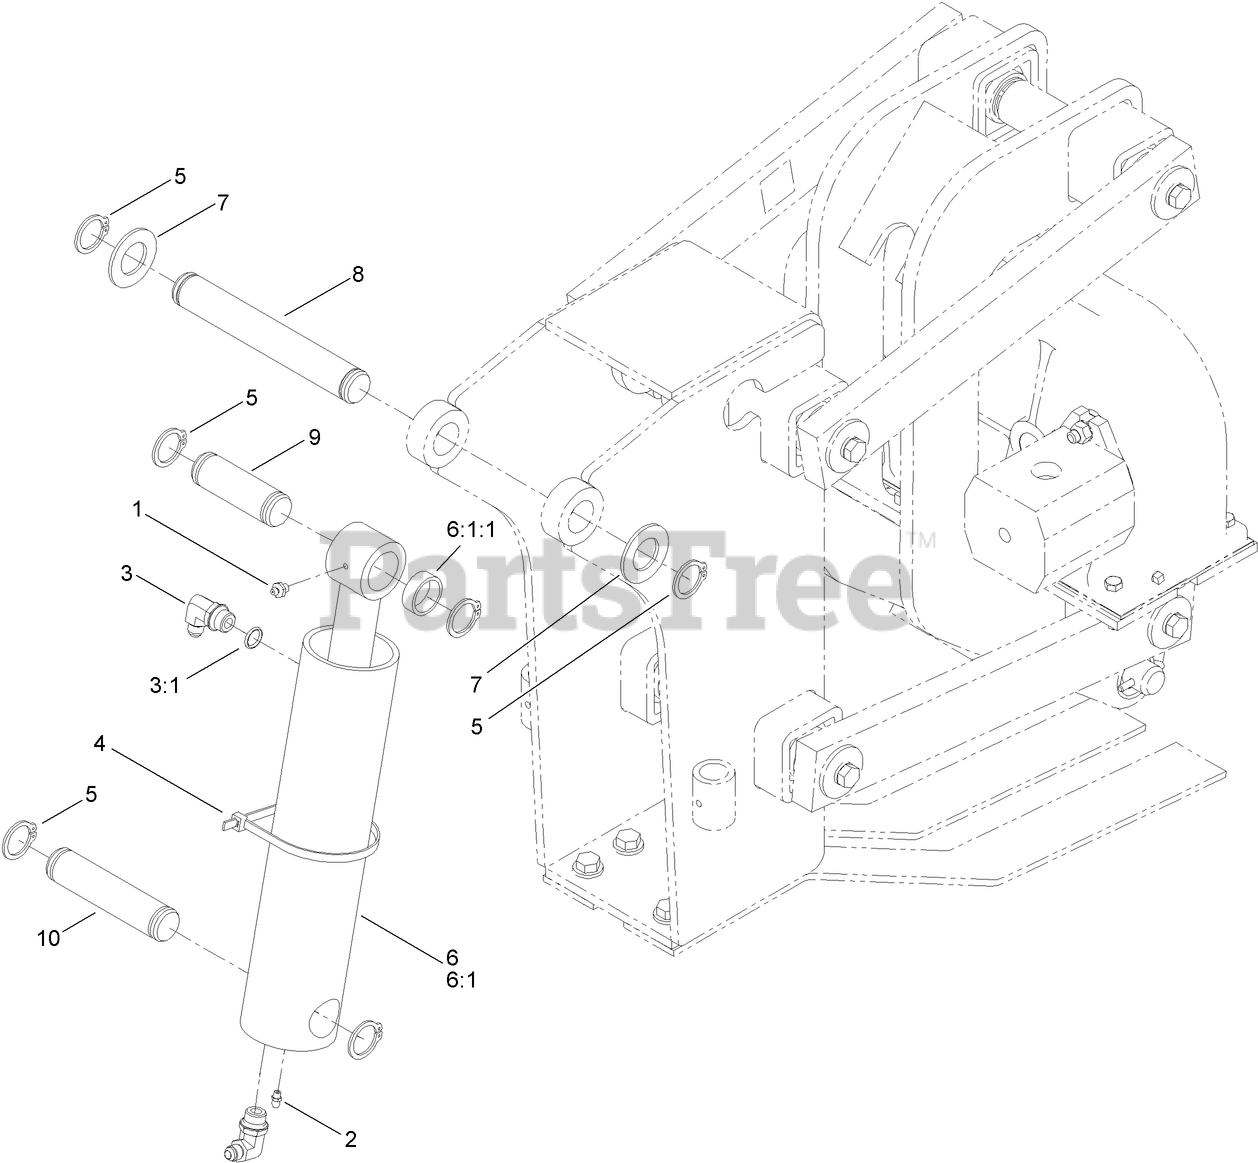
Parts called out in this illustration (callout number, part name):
1	FITTING-GREASE
2	FITTING-GREASE
3	FITTING-ELBOW, 90 DEG
3:1	O-RING
4	TIE-CABLE
5	RING-RETAINING, EXTERNAL
6	HYD CYLINDER ASM
6:1	Cylinder-Hydraulic
6:1:1	BUSHING, PRESS FIT
7	WASHER-10 GAUGE
8	PIN-LIFT
9	PIN-CLEVIS
10	PIN-CLEVIS
